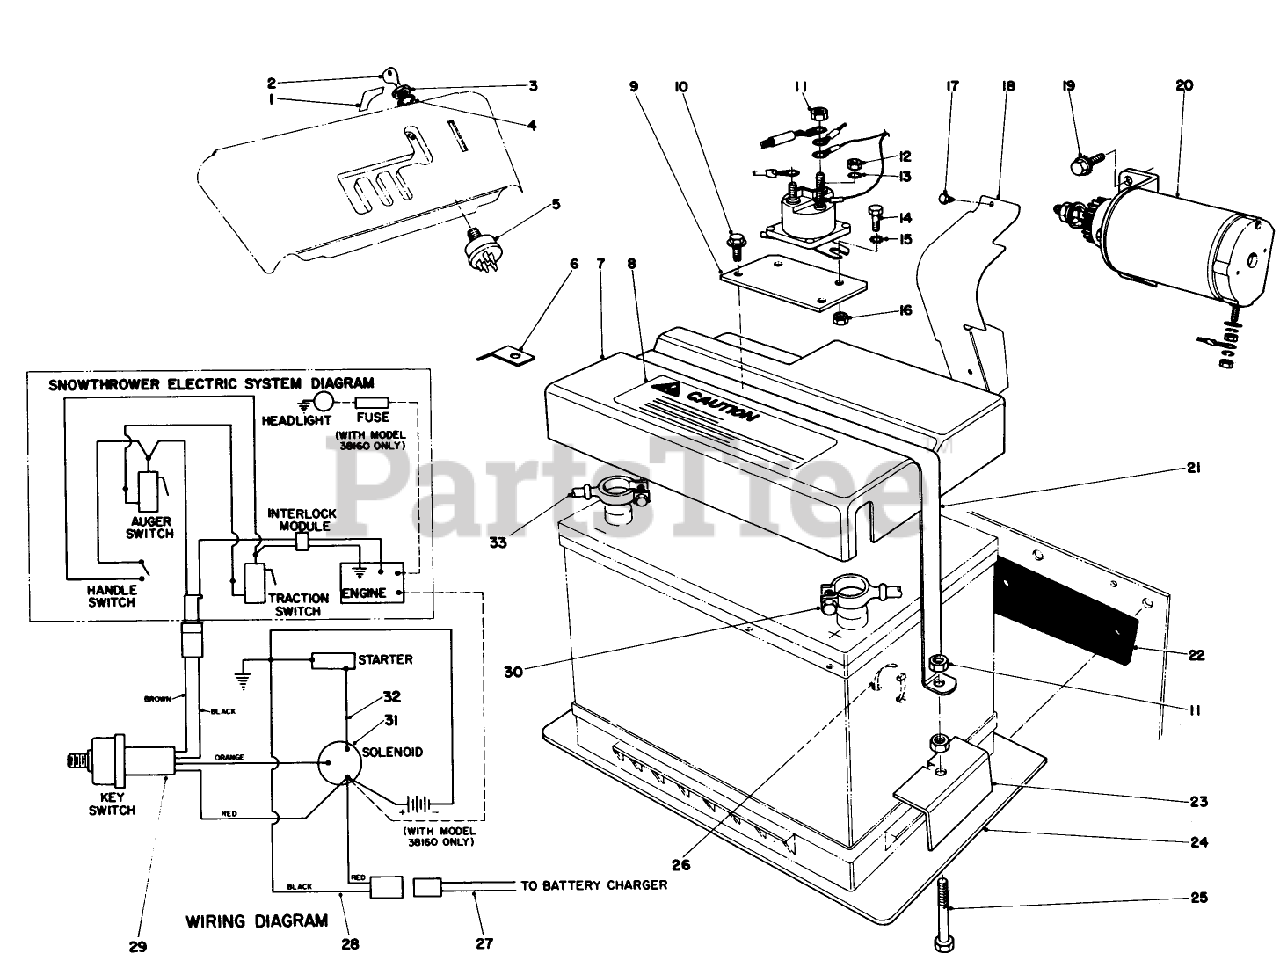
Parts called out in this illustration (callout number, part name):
3	NUT-HH
4	WASHER-LOCK
8	0630 Decal-Caution
10	SCREW-HWH
11	NUT-HEX
12	NUT-HEX
13	WASHER-LOCK, INT
14	SCREW-HH
15	WASHER-LOCK/EXT
16	NUT-LOCK, NI
18	BRIGGS 280265
19	5/16-18X3/4 HX HD SEM
20	Starter Motor Pinion Assy.
25	SCREW-HH
26	TIE-CABLE
27	MALE WIRE ASM
30	BATT-SOLENOID CABLE
31	SOLENOID
